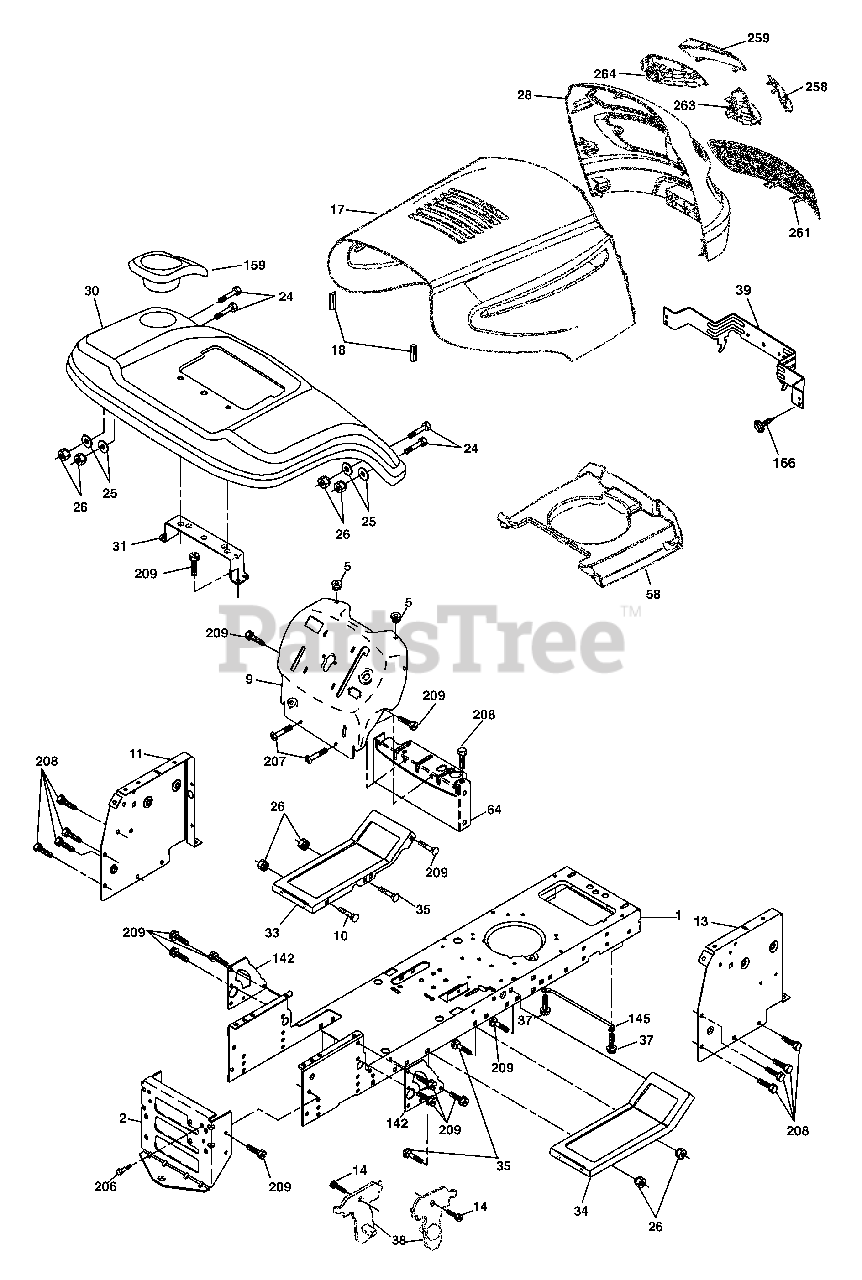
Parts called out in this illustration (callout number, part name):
1	Chassis
2	Drawbar
5	Bumper Hood/Dash
9	Dash P/L
10	Bolt Carriage 3/8-16 x 1
11	Panel Dash Lh
14	Screw Thdrol 3/8-16 x 1/2
17	Hood
18	Bumper Hood
24	Bolt Fin Hex 3/8-16 unc x 1 Gr. 5
26	Nut Lock Hex W/Ins 3/8-16 unc
28	Grille/Lens Asm
30	Fender
31	Bracket Fender
33	Footrest LH
34	Footrest RH
35	Bolt RDHD SHT SQNK 3/8-16 x 3/4
37	Screw Thdrol 6/16-18 x 1/2 TYT
38	Bracket Asm Pivot Mower Rear
39	Bracket Pivot
58	Duct Air
64	Dash Lower STLT
142	Plate Reinforcement STLT
145	Rod Pivot Chassis/Hood
159	Cupholder
166	Screw Hwhd Hi-Lo #13-16 x 3/4
206	Bolt Shoulder 5/16-18
208	Screw Thdrol 3/8-16 x 1/2
209	Screw Hexwsh Thdr 3/8-16 x 3/4
258	Lens Grille Pro RH
259	Lens Grille Pro LH
263	Bezel Grille LH
264	Bezel Grille RH
